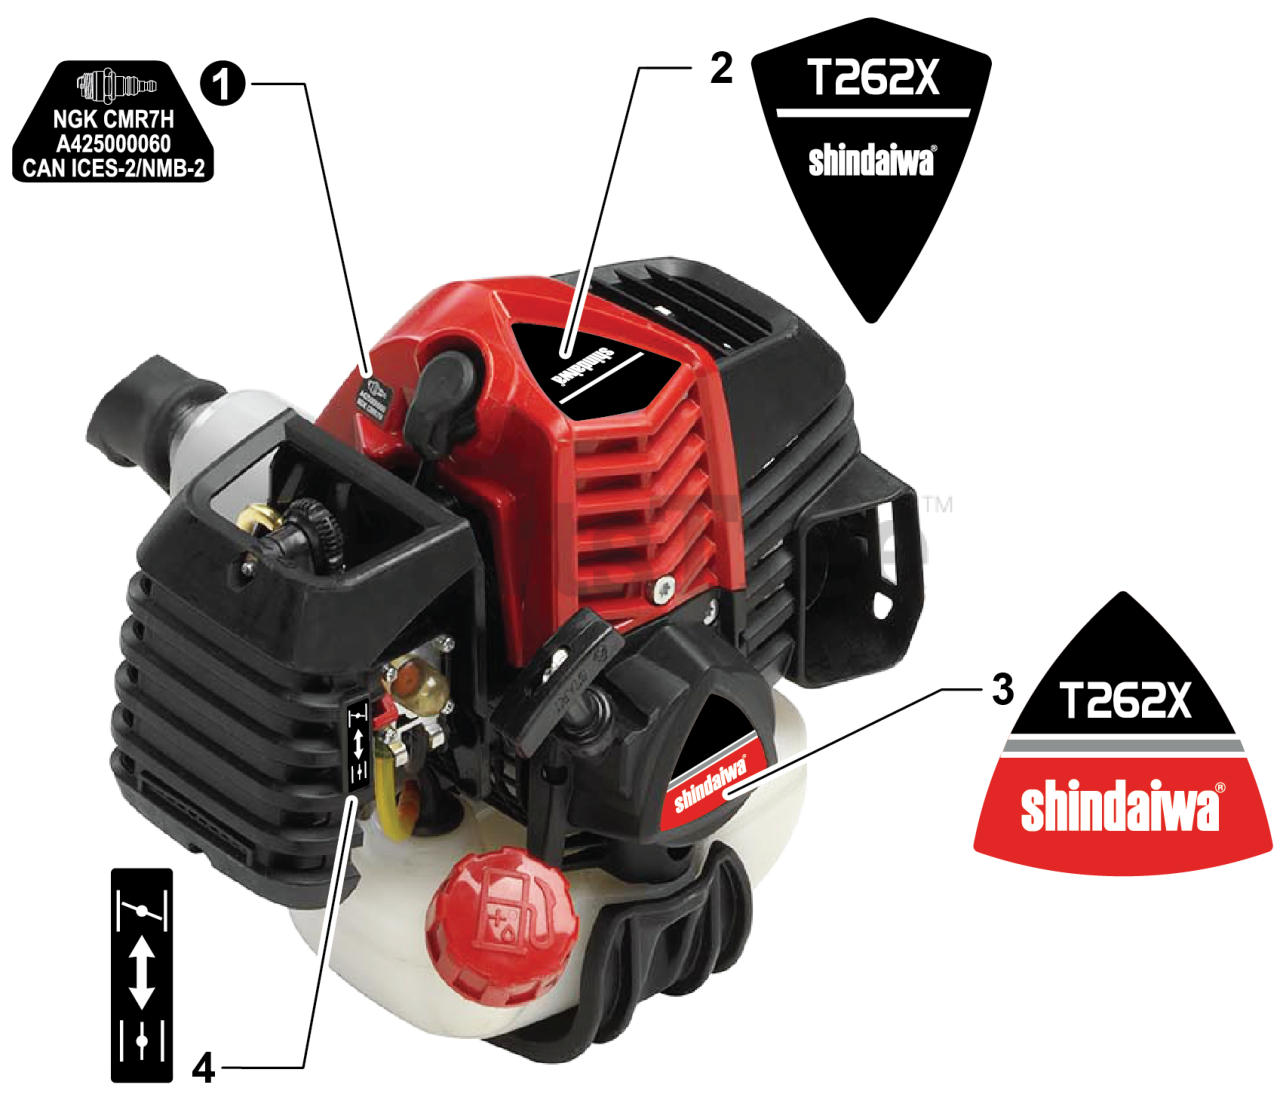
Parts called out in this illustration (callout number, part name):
1	LABEL - SPARK PLUG - CMR7H
2	LABEL - MODEL T262X
3	LABEL - RECOIL STARTER
4	LABEL - CHOKE
